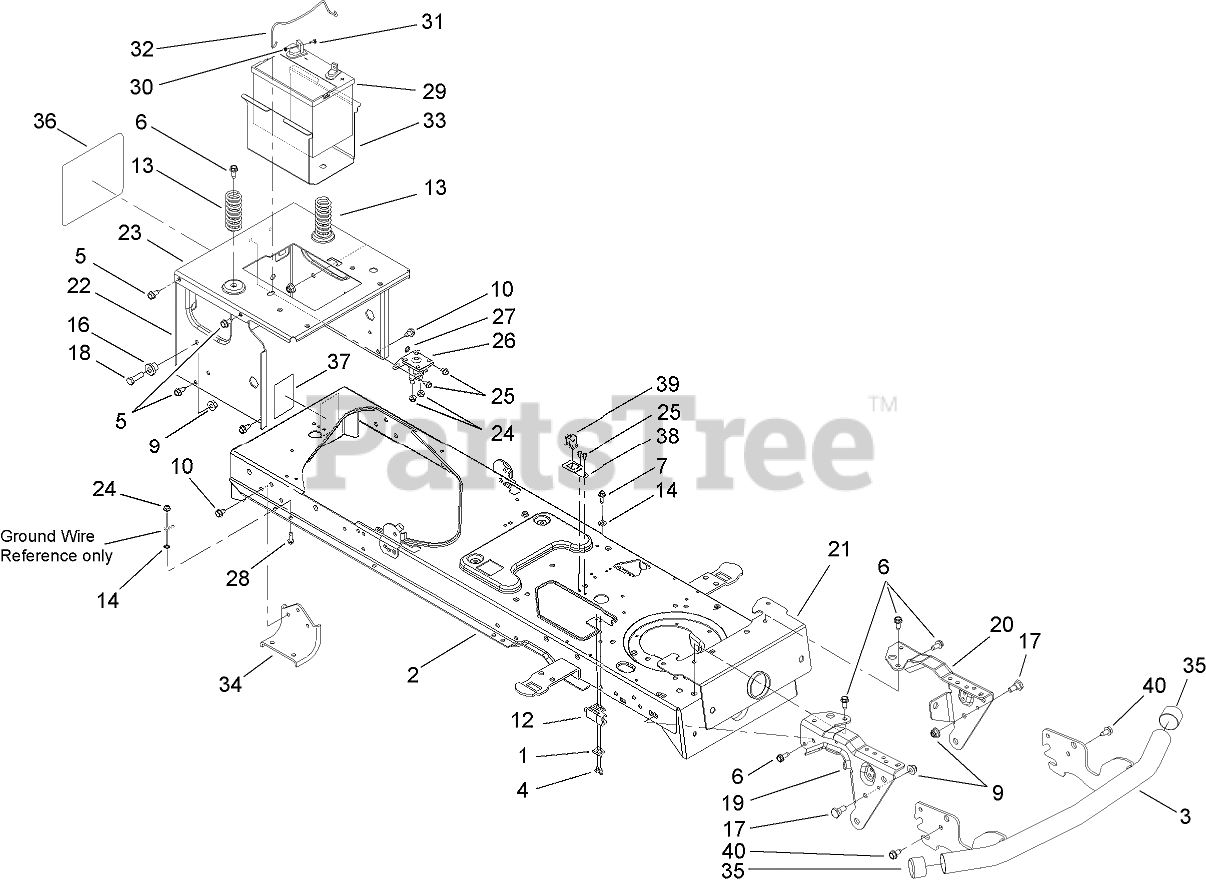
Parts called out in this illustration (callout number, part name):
1	PLATE-SWITCH
2	LOWER FRAME ASM
3	BUMPER ASM
4	SCREW-TAP
5	SCREW-HWH
6	SCREW-HWH
7	SCREW-HWH
9	NUT-LOCK, FLANGE
10	SCREW-TAP
12	SWITCH-INTERLOCK
13	SPRING-COMPRESSION
14	WASHER-LOCK, EXTERNAL
16	SPACER-SHOULDER
17	BOLT-SHOULDER
18	SCREW-HH
19	BRACKET-PIVOT, SUPPORT
20	BRACKET-PIVOT, SUPPORT
21	BRACKET-PIVOT, BAR
22	SUPPORT-FRAME, REAR
23	BRACKET-FRAME, SEAT
24	NUT-LOCK, FLANGE
25	SCREW-HWHTF
26	SOLENOID-12V, 2 Post 1 Tab
27	WASHER-LOCK, EXTERNAL
28	SCREW-TAP
29	BATTERY-245, CCA (DRY FLAT TOP)
30	NUT-SEMS
31	BOLT-CARRIAGE
32	ROD-HOLDDOWN, BATTERY
33	TRAY-BATTERY
34	BRACKET-AXLE
35	CAP-HUB
36	DECAL-TORO
37	DECAL-BYPASS
38	BRACKET-SWITCH, PARKING BRAKE
39	SWITCH-MOUNT, SNAP
40	SCREW-HH, TAP
